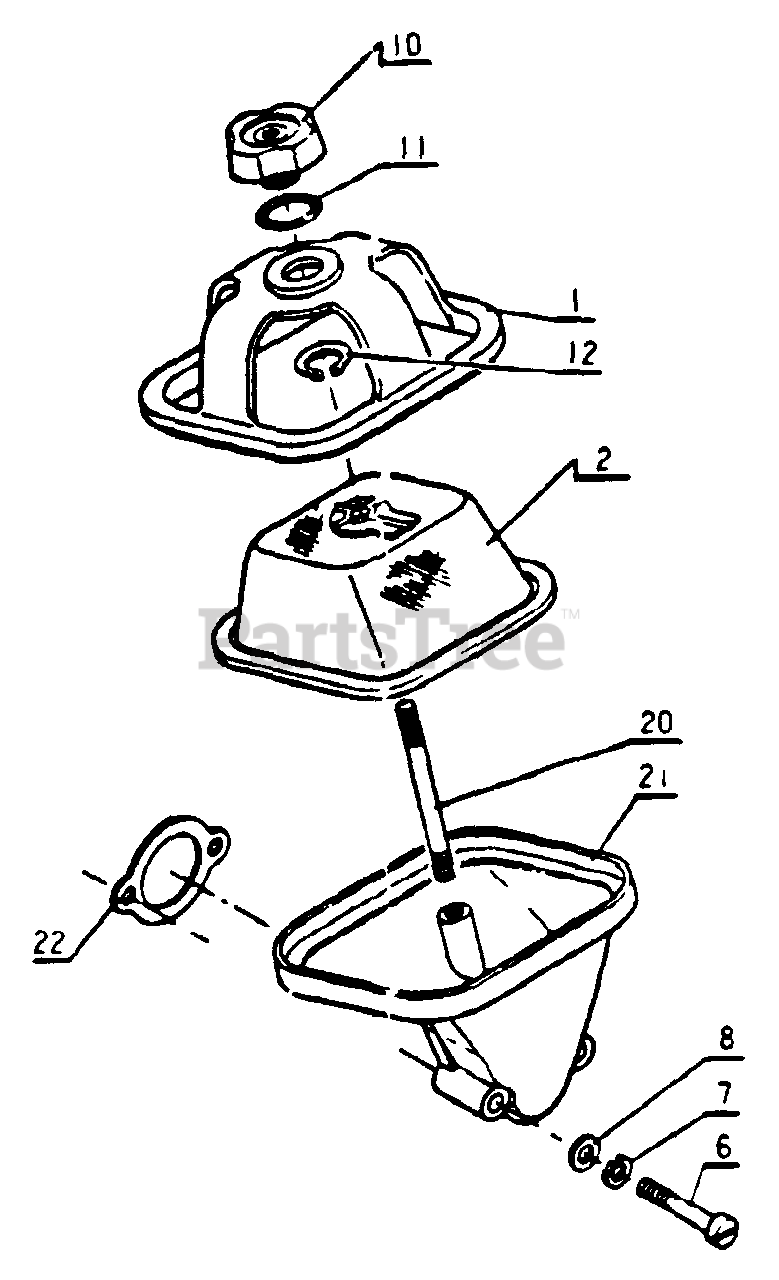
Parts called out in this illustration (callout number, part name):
1	COVER, AIR FILTER
2	FILTER, AIR
6	SCREW - 5X10
7	LOCKWASHER - 5
8	WASHER - 5
10	WINGNUT
11	O-RING
12	RING, RETAINING - 11
20	STUD
21	CASE, AIR FILTER
22	GASKET
